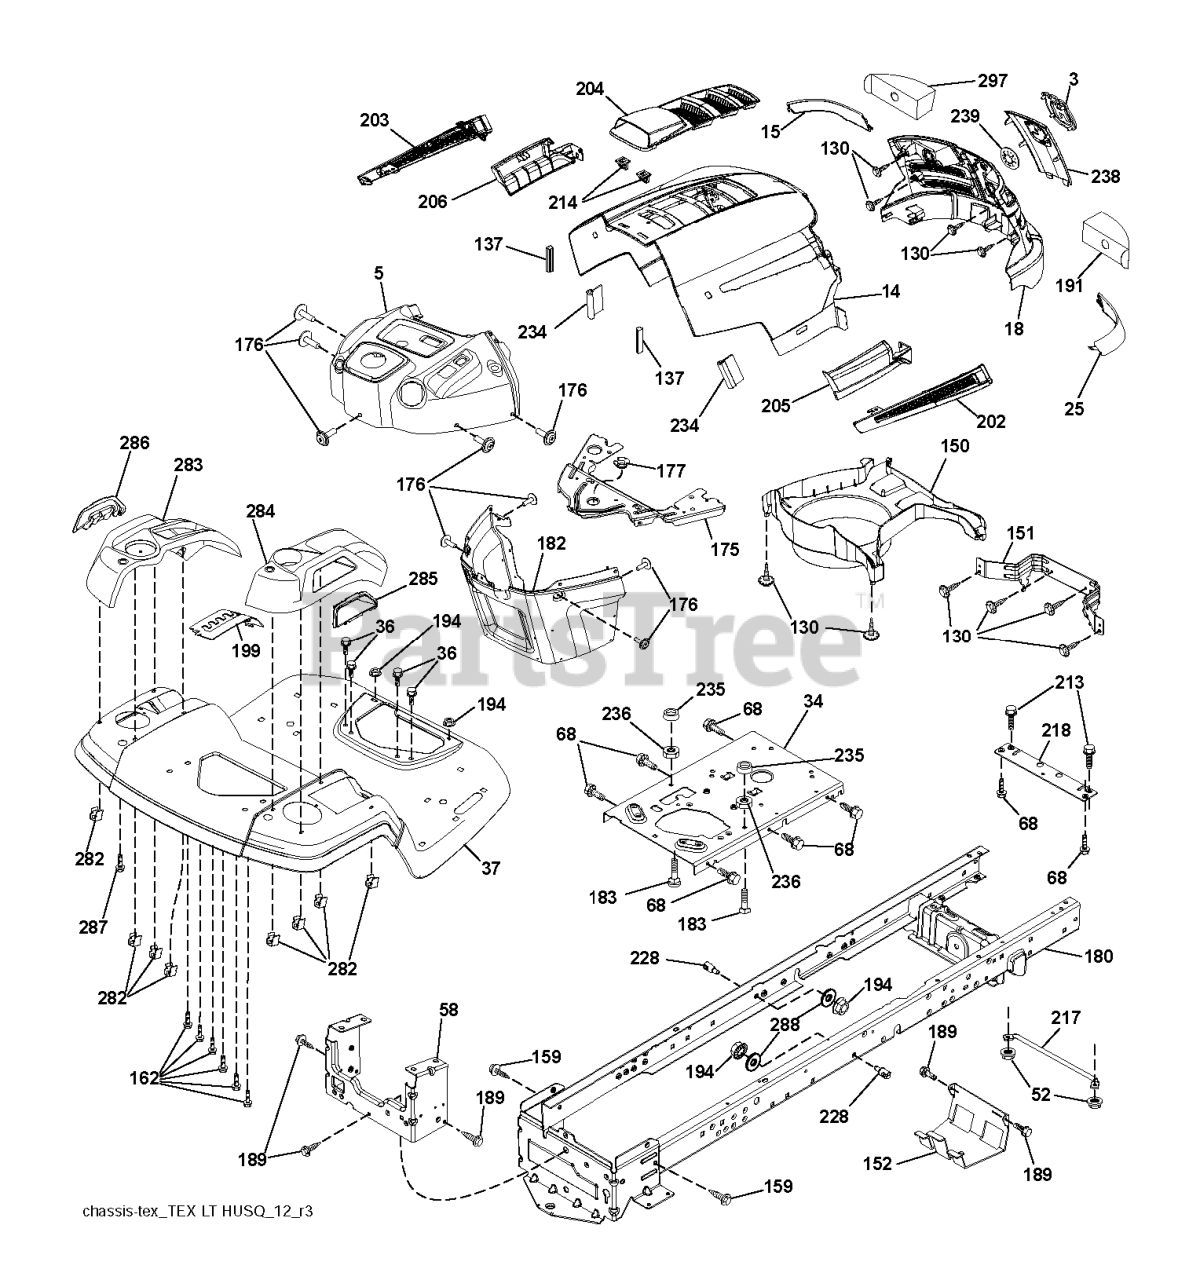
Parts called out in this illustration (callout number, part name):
3	RP LOGO
5	DASH
14	HOOD
15	LENS.HUSQVARNA LT.LH
18	RP GRILLE/LENS ASM.
25	LENS.HUSQVARNA LT.RH
34	PLATE.ENGINE.WELDED.CHASSIS
36	SCREW 5/16"
37	RP FENDER.TLT.FS.W/CPH.422
52	LOCKNUT
58	DRAWBAR UPPER 2PC SMALL FENDER
68	Screw 5/16-18 x 1/2 Hex, Self Tapping 5/16-18 x 1/2
130	SCREW.#10 X 0.750.BOS
137	BUMPER DASH
151	BRACKET PIVOT
152	SHIELD.BROWNING.W/TEX
159	SCREW, 3/8-16X3/4
162	SCREW.HI-LO.CONSOLE
175	CROSSMEMBER
176	SCREW.#10-24X5/8.RN.QU
177	BUSHING STEERING
180	CHASSIS.WLDMNT.14GA.2PC.18".TI
182	DASH.LOWER.PREDATOR LT
183	BOLT.5/16-18X1-1/4 FULL.THREAD
189	SCREW
191	INSERT.REFLECTIVE.RH.
194	NUT LOCK HEX FLANGE 5/16-18
199	PLATE.DECK.LIFT.HUSQ.LT
202	VENT SIDE HOOD LH
203	VENT SIDE HOOD RH
204	VENT TOP HOOD
205	SKIRT SIDE RH
206	SKIRT SIDE LH
213	BOLT
214	CLIP.RETAINER.TINNER.
217	ROD.PIVOT.HOOD
218	X-PIECE.HOOD.STOP.NON/
228	STUD.FASTNER.W/ANTI-ROTATE
234	BUMPER.HOOD.TEX.HUSQVARNA
235	SPACER FENDER
236	NUT.CENTERLOCK.5/16-
238	TRIM
282	CLIP.RETAINER.CONSOLE.LT.HUSQ
283	CONSOLE.DECK.LIFT.HUSQ.N/FR.GR
284	CONSOLE.CNTRL.
285	CONSOLE INSERT RH
286	CONSOLE.INSRT.LH.HUSQ.LT.BLACK
287	SCREW 1/4X20
288	WASHER
297	INSERT REFLECTIVE
